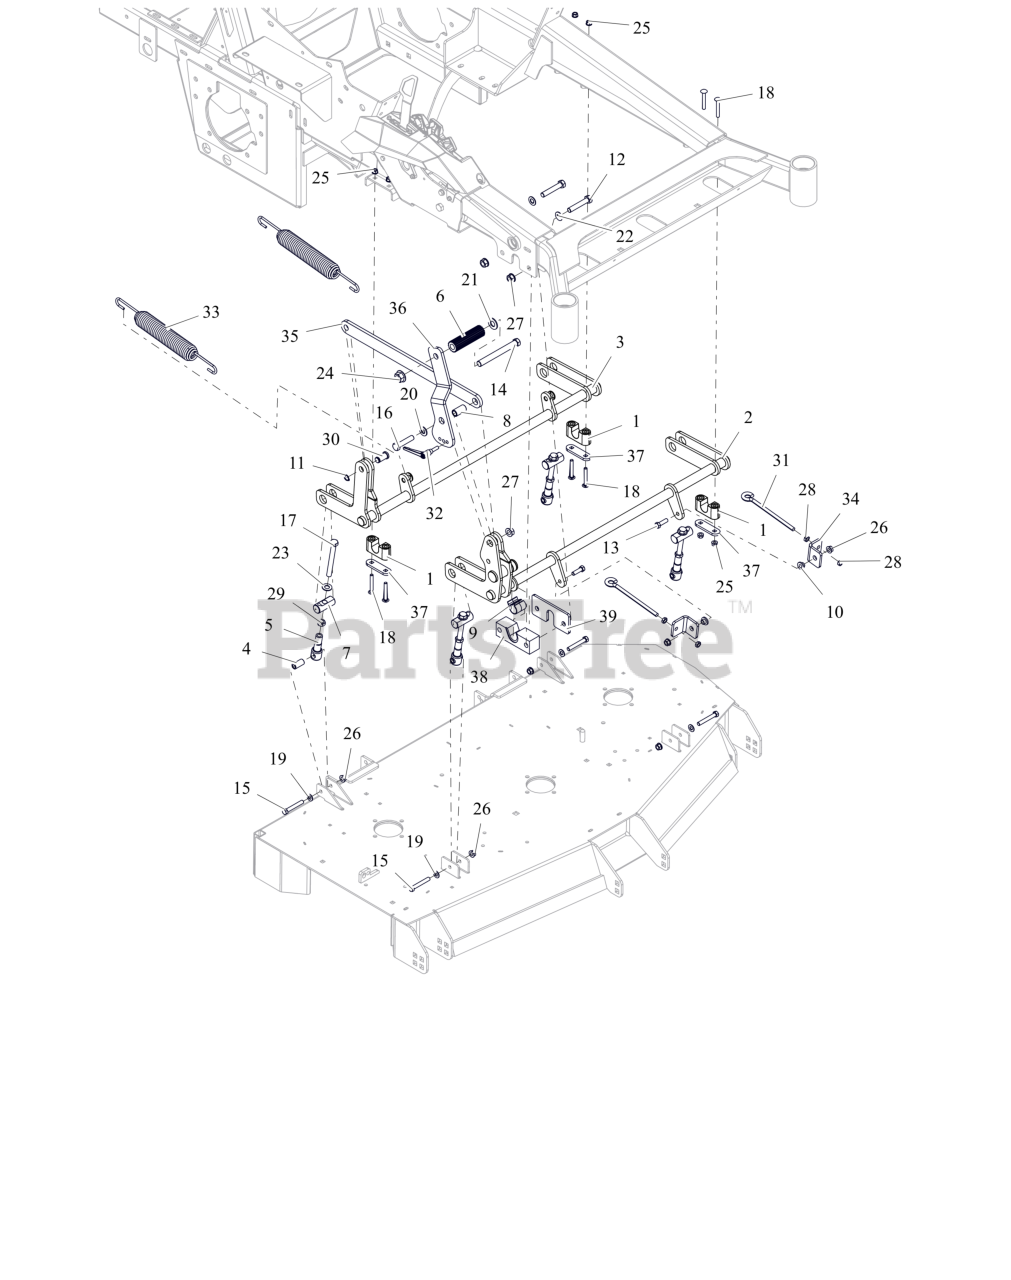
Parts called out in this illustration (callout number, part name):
1	ASM-BUSHING, DECK LIFT
2	WLDMT, FRONT DECK LIFT (BLACK)
3	WLDMT, REAR DECK LIFT (BLACK)
4	SPACER, DECK LEVELING
5	LINK, DECK LIFT FORMED
6	ROD, FOOT PEDAL (BLACK)
7	PIN, DECK LIFT
8	SPCR, SLV .531x.75x1.449
9	BUSHING, SHAFT
10	BSHG-FLG .385X.500X.875X.406
11	RG-RTNG-EXT .625X.050
12	BLT,HEX .50-13X2.75 G5 ZCC
13	BLT, HEX .38-16X1.25 G5 ZCC
14	BLT, HEX .62-11X5.50 G5 FBP
15	BLT, HEX .38-16X2.50 G8 ZCC
16	BLT, HEX .50-13X2.25 G5 ZCC
17	BLT, HEX 0.5-13X4.5S GR5 ZCC
18	BLT, RHSSN.31-18X2.25 G5 ZCC
19	WSHR,FLT .406X.812X.065 ZCC
20	WSHR,FLT .531X1.062X.095 ZCC
21	WSHRFLT 5/8SAE CARBHARD FBP
22	WSHR, FLT .531X1.00X.063 ZCC
23	WSHR, FLT .557X1.040X.102 ZCC
24	NUT,FLG-TOP LK .625-11 FBP
25	NUT,LK-CTR-FLG .31-18 GF ZCC
26	NUT-LK-CTR-FLG .375-16 GF ZCC
27	NUT-LK-CTR-FLG .500-13 GG ZCC
28	NUT-JAM .375-16 G2 ZCC
29	NUT-JAM .500-13 G2 ZCC
30	PIN, CLEVIS .625 SNAP RING
31	BOLT, .38-16X6.00 .62 DIA EYE
32	HANDLE, CLAMPING
33	SPRG, DECK LIFT
34	BRKT, SPRING ANCHOR (BLACK)
35	LINK, DECK LIFT (BLACK)
36	ARM, ADJUSTABLE FOOT PEDAL (BLACK)
37	PLATE, PT600 BEARING SUPPORT (BLACK)
38	BUSHING, DECK LIFT
39	PLATE, SHAFT RETAINER (RED)
